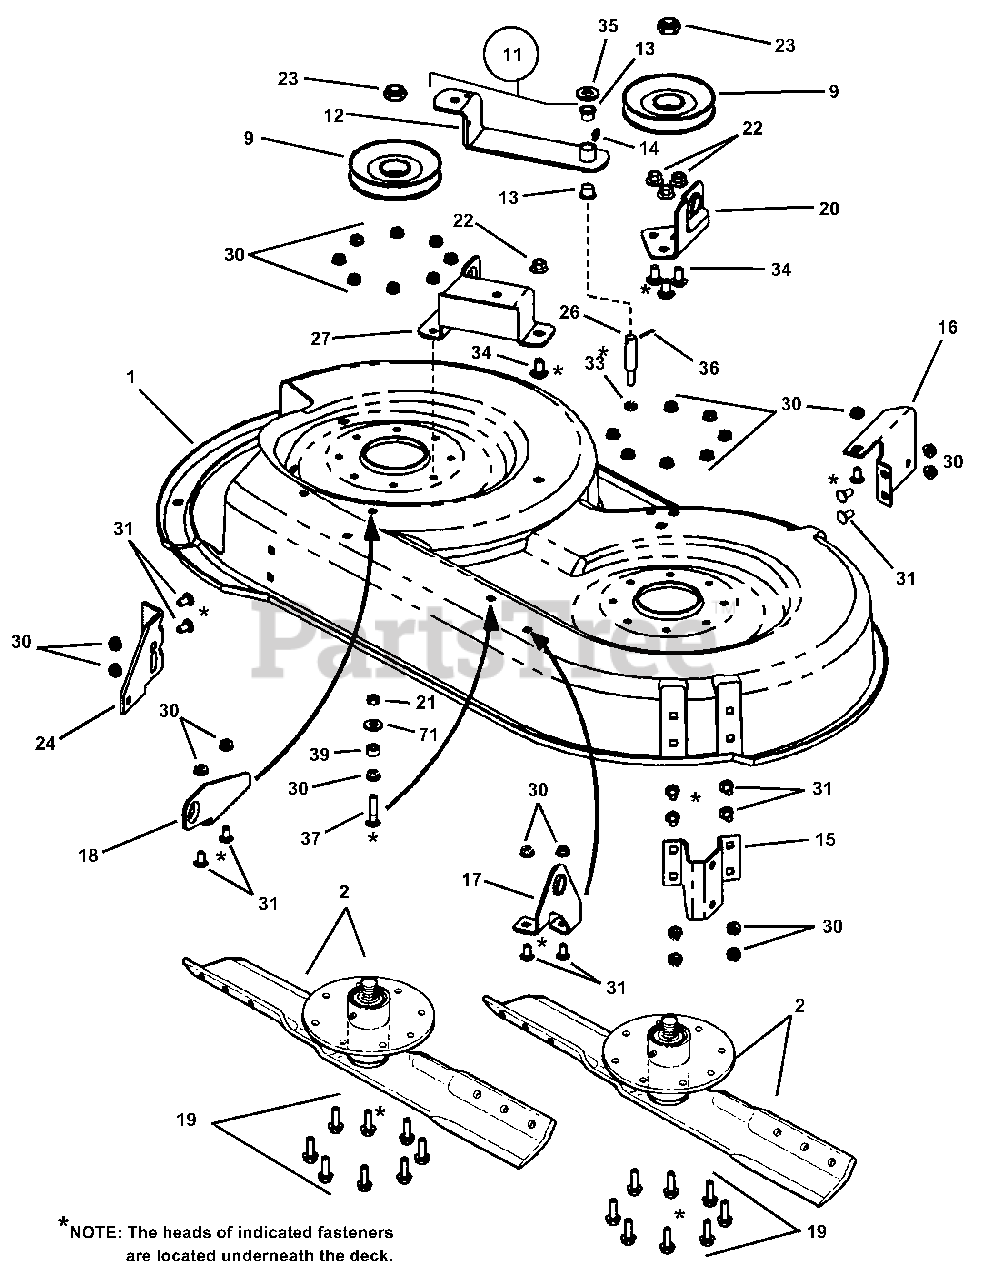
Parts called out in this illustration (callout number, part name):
1	DECK, Painted Shell w/Decals
2	ASSEMBLY, Spindle
9	PULLEY, 4-1/2" O.D., A/B Groove
11	ASS'Y, Idler Arm
12	WELDMENT, Idler Arm
13	BUSHING, 1/2" Nylon
14	LUBE FITTING, Straight (press-fit for .187 dia. Hole)
15	BRACKET, Gage Wheel
16	BRACKET, Left Hand Wheel
17	BRK'T, 38" Deck Lift, LH Front
18	BRK'T, 38" Deck Lift, RH Front
19	SCREW, 5/16-18 x 1" Hex Head Cap, Grade 5
20	BRK'T, Left Hand Rear Lift Arm
21	NUT, 5/16-18 Hex Center Lock Grade 5
22	NUT, 3/8-16 Hex Flange Lock
23	NUT, 5/8-18 Hex Nyloc
24	BRACKET, Gage Wheel
26	STUD, Idler (5/16-24 thread)
27	BRACKET, Stationary Idler
30	NUT, 5/16-18 Hex Flange Lock, Grade 5
31	BOLT, 5/16-18 x 5/8" Short Neck Carriage, Grade 5
33	NUT, 5/16-24 Hex Center Lock
34	BOLT, 3/8-16 x 3/4" Short Neck Carriage, Grade 5
35	WASHER, 1/2" x 1-1/16" Flat
36	COTTER-PIN, 3/32 x 3/4"
37	BOLT, 5/16-18 x 1-1/2" Short Neck Carriage, Grade 5
39	SPACER, .340 I.D. x .630 O.D. x .310 Thick
71	WASHER, 3/8" I.D. x 7/8" O.D. Flat
